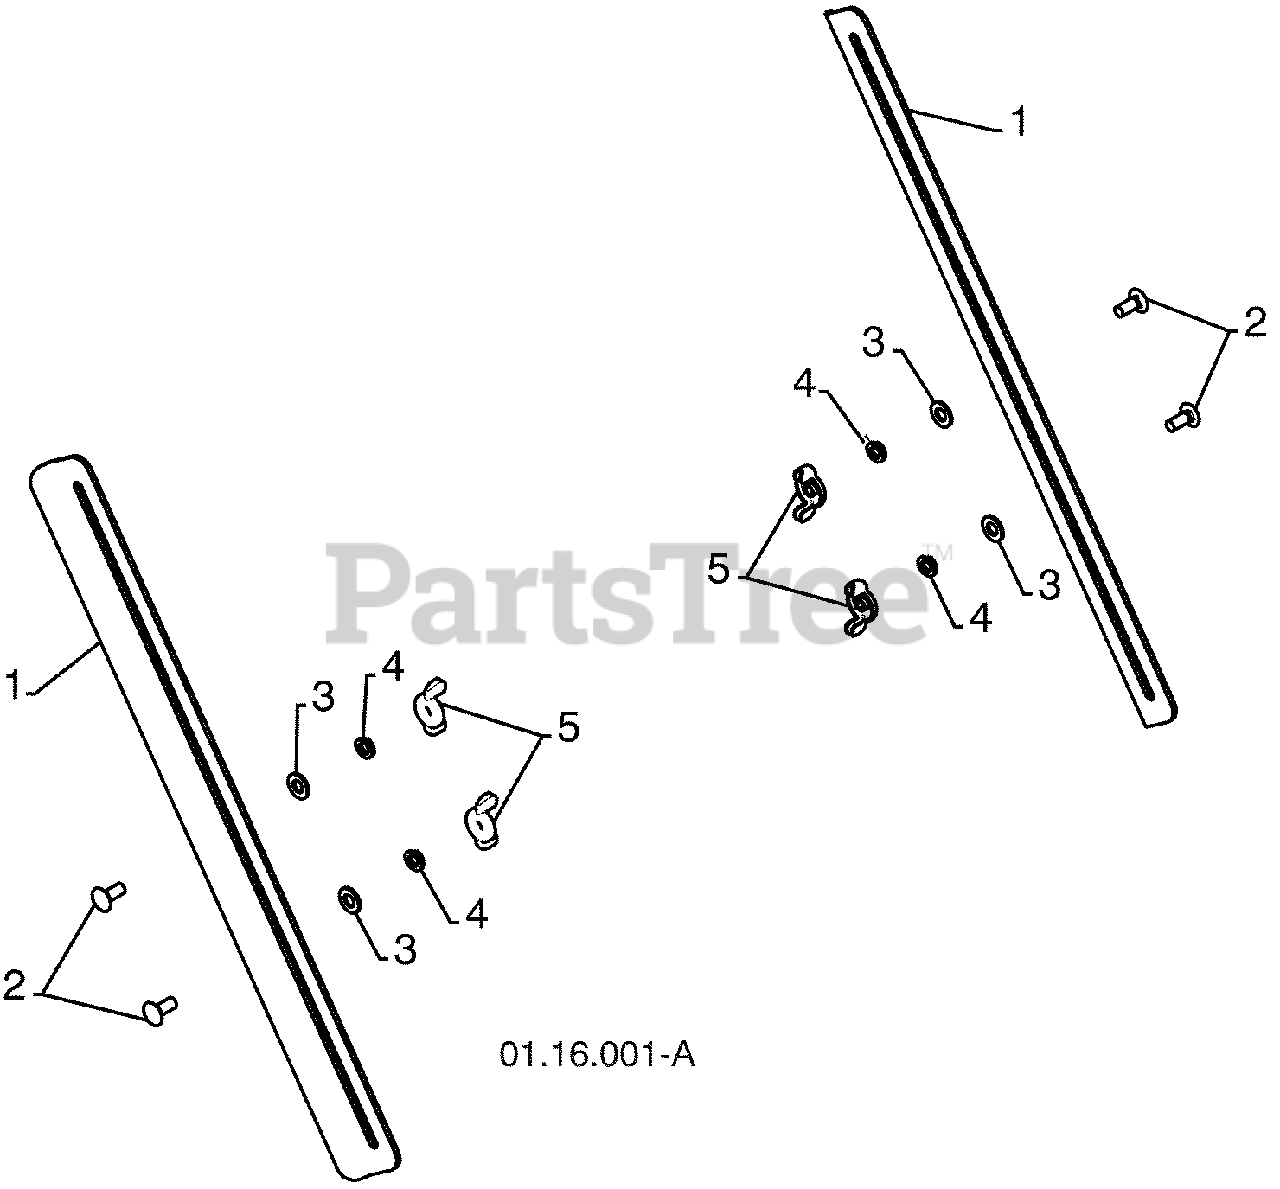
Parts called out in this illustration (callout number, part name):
1	DRIFT CUTTER BAR
2	CARRIAGE BOLT 5/16-18 X .750
3	PLASTIC WASHER
4	LOCKWASHER 5/16
5	NUT 5/16-18
